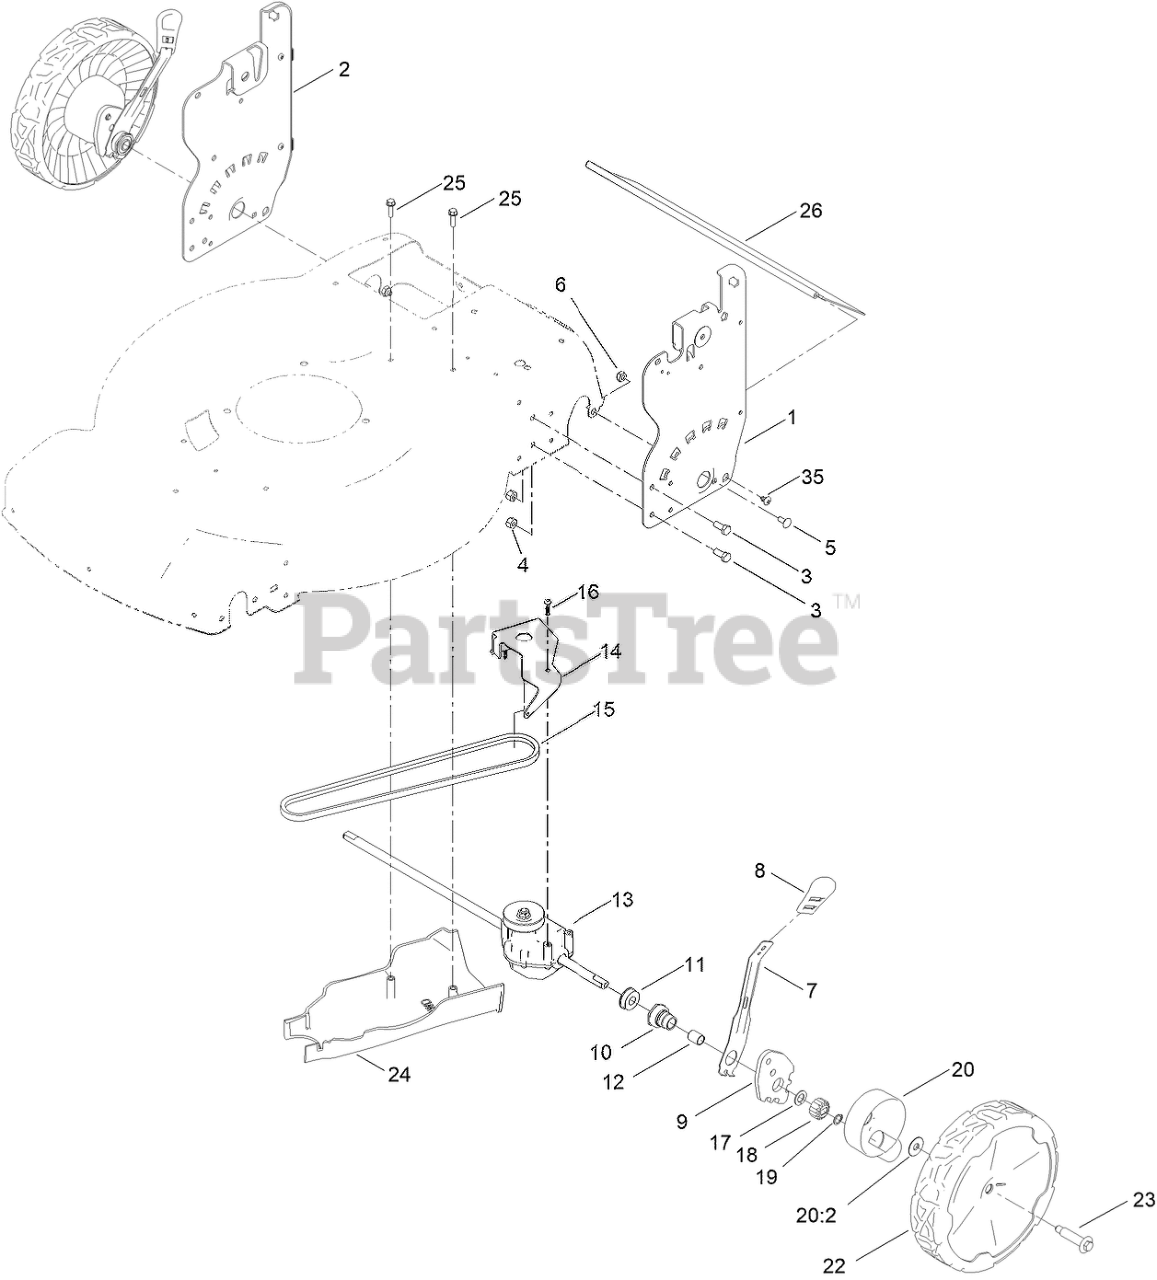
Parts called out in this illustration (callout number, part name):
1	PLATE-HOC, LH
2	PLATE-HOC, RH (ISO)
3	SCREW-HH
4	NUT-LOCK, NI
5	SCREW-CARR
6	NUT-LOCK, NI
7	ARM-SPRING
8	KNOB-HOC
9	ARM-PIVOT, REAR
10	RETAINER-BUSHING, HOC
11	BEARING-BALL
12	BUSHING-SLEEVE
13	TRANSMISSION-RWD
14	BRACKET-TRANSMISSION
15	V-BELT
16	SCREW-PLASTITE
17	WASHER-THRUST
18	GEAR-PINION, 15T
19	RING-RETAINING
20	ASM-COVER, GEAR (DK GRAY)
20:2	WASHER-STEPPED
22	ASM-9.65" WHEEL, GEARED
23	WHEEL BOLT
24	COVER-BELT, RWD
25	SCREW-HWH
26	SHIELD-TRAILING
35	SCREW-PTH
